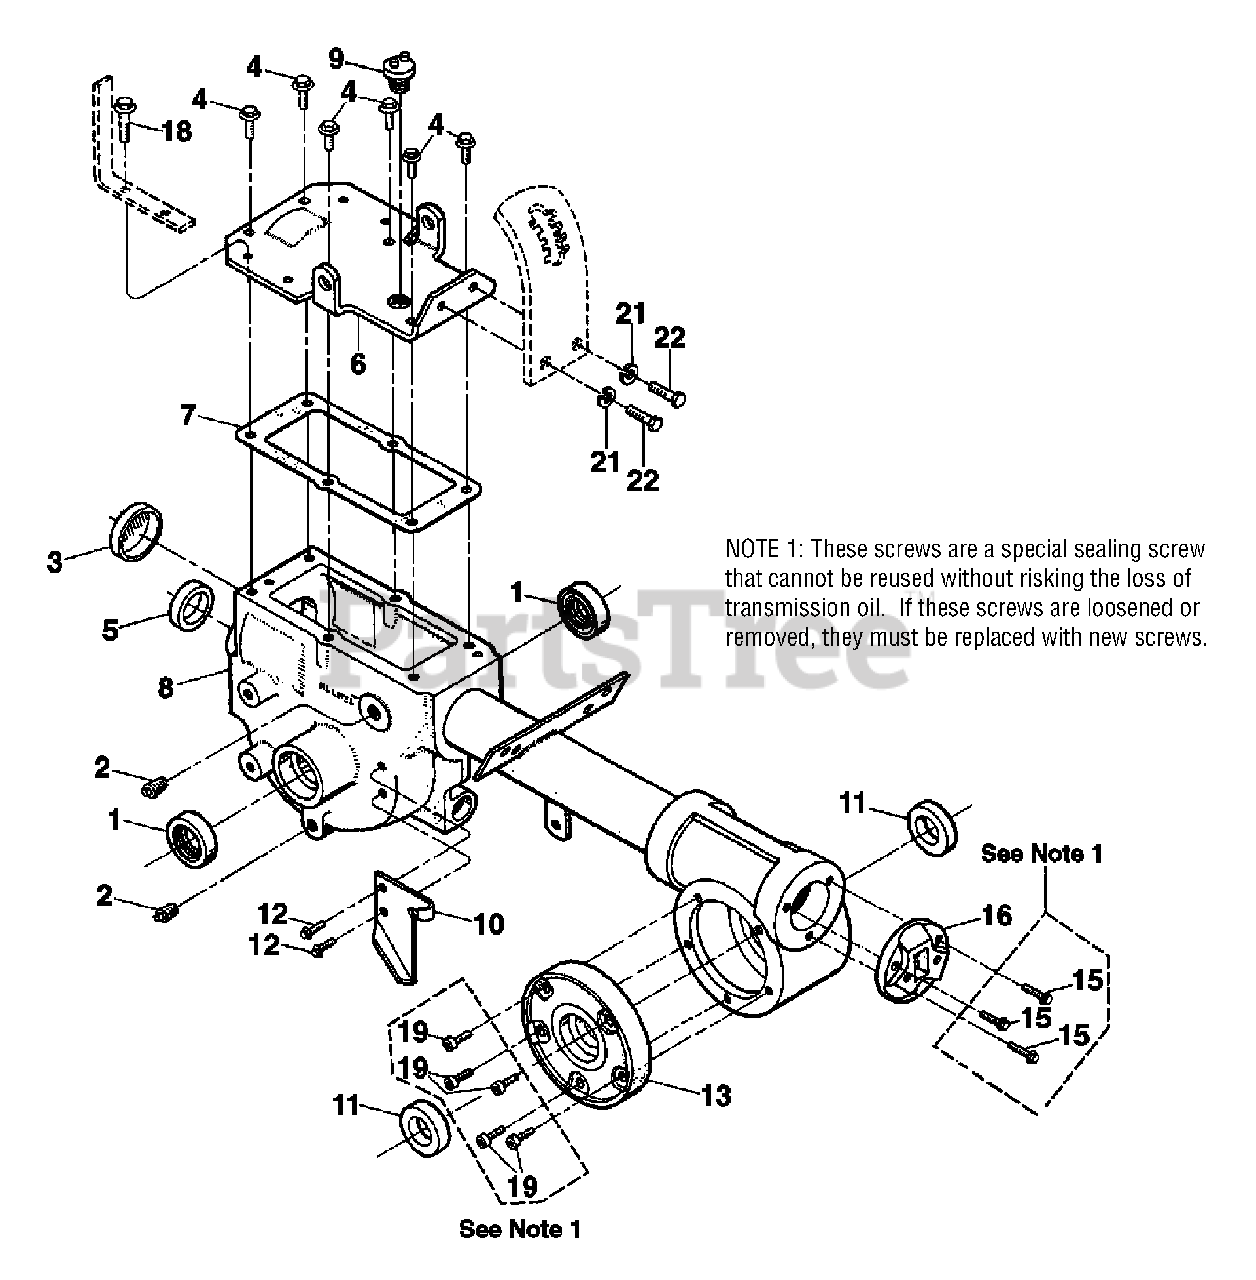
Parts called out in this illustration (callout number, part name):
1	Oil Seal (Double Lip), Wheel Shaft
2	Pipe Plug, 1/4,
3	Seal, Transmission Bore
4	Hex Flange Screw, 5/16-18 x 3/4
5	Oil Seal, Input Pinion Shaft
6	Transmission Cover (Incl. four Ref. 18 and two ea. Refs. 21 & 22)
7	Gasket, Transmission Top Cover
8	Transmission Case Assy. (Incl. Tube and Rear Housing)
10	Mounting Plate, Wheel Clutch Cable
11	Oil Seal, Tiller Shaft
12	Hex Flange Screw, 5/16-18 x 5/8
13	Tiller Housing Cover, left side
15	Screw Kit: Incl. three 1/4-20 x 7/8 Self-Sealing Screws
16	Rear Bearing Cap
17	Gasket, Rear Bearing Cap, .010" Thick
18	Hex Flange Screw, 5/16-18 x 1
19	Screw Kit Incl. five 1/4-20 x 5/8 Self-Sealing Screws
21	Lockwasher, 3/8
22	Hex Hd. Screw, 3/8-16 x 3/4
